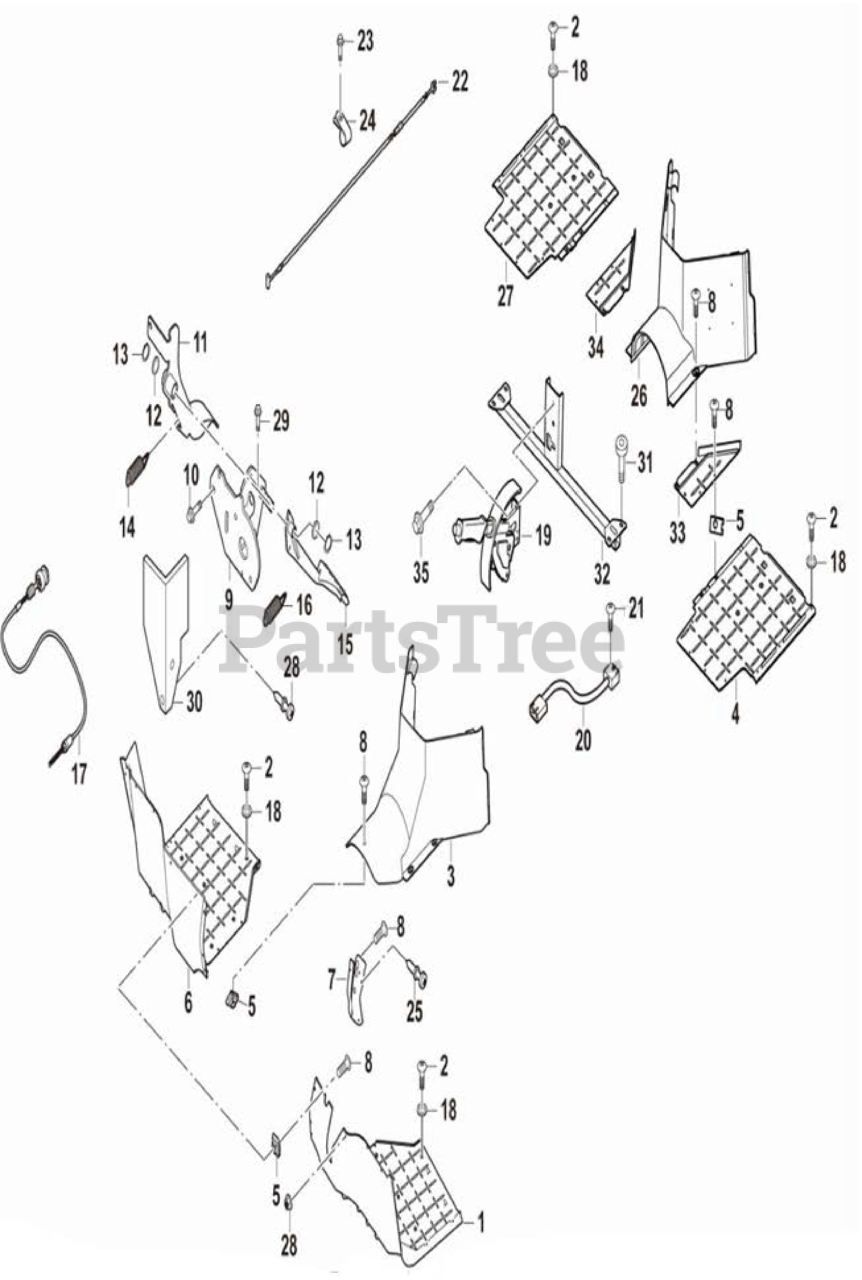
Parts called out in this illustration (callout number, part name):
1	Left Footrest board
2	Cross Large Plate Head Screw M5X16
3	Footrest Cover(Middle)
4	Protective cover rear left footrest
5	Nut clamp M6X2
6	Right Footrest board
7	Dustproof Pad H, Brake Pedal
8	Cross Large Plate Head Screw M6X16
9	Brake Pedal Mounting Plate
10	Hexagon Flange Bolt M8X16
11	Accelerator Pedal
12	Flat Washer 15X22X1
13	Split Washer 12
14	Tension Spring B
15	Brake Pedal
16	Tension Spring 0
17	Accelerator Dragline R
18	Flat Washer 5
19	Parking System
20	Microswitch
21	Cross Plate Head Screw M3X16
22	Dragline Assy M, Parking Brake
23	Hexagon Flange Bolt M6X16
24	Fixing Clip II,Fuel Pipe
25	Expansion bolt(Plastic)
26	Middle broad Seat
27	Rear right footrest protective cover
28	Hexagon Flange Self-Lock Nuts (With Metallic Insert) M6
29	Hexagon Flange Bolt M8X20
30	Main Pump Backplate, Disc Brake
31	Hexagon Socket Head Screw M8X20
32	Mounting Bracket,Parking
33	Left Lower Backplate, Rear Seat
34	Right Lower Backplate, Rear Seat
35	Hexagon Flange Bolt M8X20
